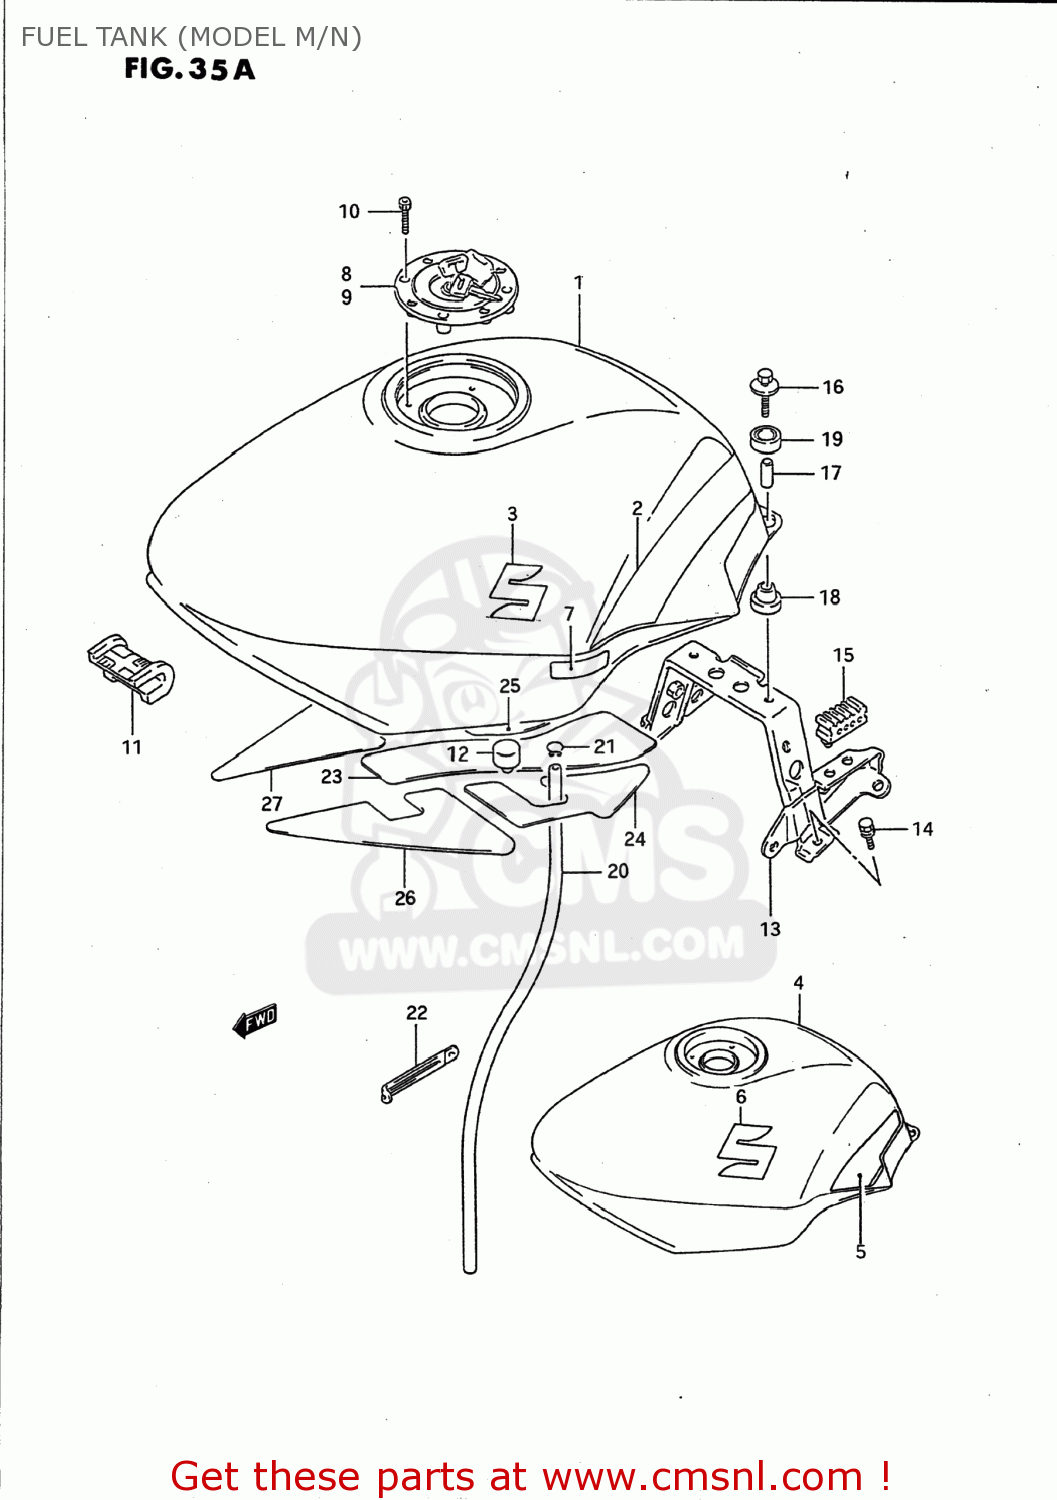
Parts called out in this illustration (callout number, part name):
1	TANK ASSEMBLY,FUEL
2	TAPE,FUEL TANK STRIPE
3	EMBLEM,FUEL TANK
4	TANK ASSEMBLY,FUEL
5	TAPE SET,FUEL TANK
6	EMBLEM,FUEL TANK
7	PROTECTOR,FUEL TANK,LEFT
8	CAP SET,FUEL TANK
9	CAP SET,FUEL TANK
10	BOLT(5X20)
11	CUSHION,FUEL TANK FR
12	CUSHION
13	BRACKET,FUEL TANK RR
14	SCREW
15	CUSHION,SEAT(40X20X15)
16	BOLT
17	SPACER
18	CUSHION
19	CUSHION
20	HOSE,FUEL TANK WATER DRAIN
21	CLIP
22	CLAMP(L:120 T:1.0)
23	HEATSHIELD,CTR
24	HEATSHIELD,RR,L
25	HEATSHIELD,RR,R
26	HEATSHIELD,FR,L
27	HEATSHIELD,FR,R
